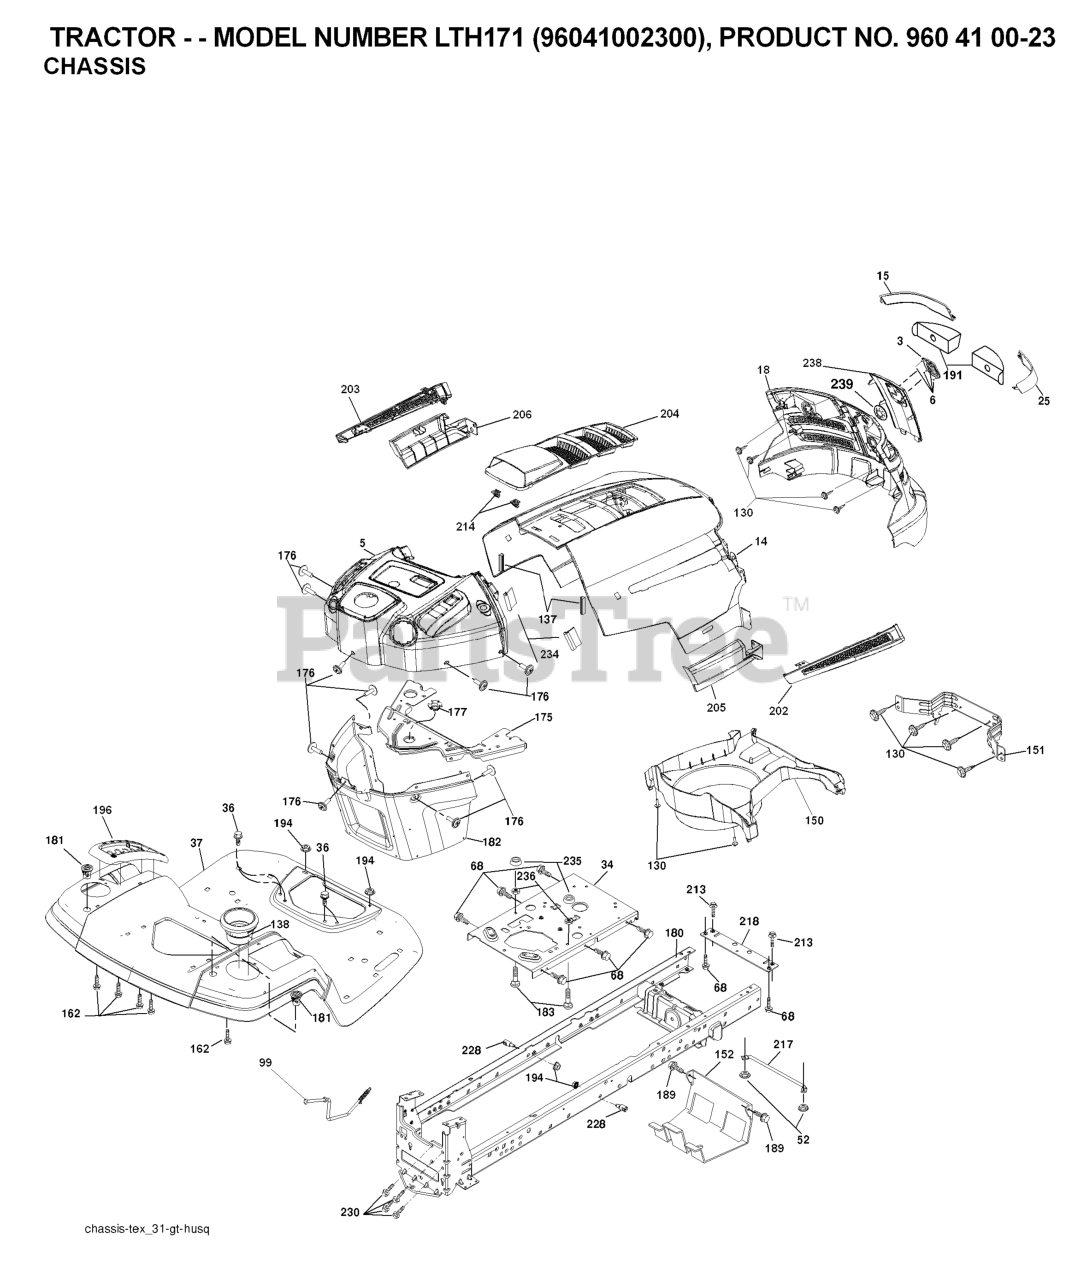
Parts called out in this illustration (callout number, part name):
3	RP LOGO
5	DASH
14	HOOD
15	LENS.HUSQVARNA LT.LH
18	RP GRILLE/LENS ASM.
25	LENS.HUSQVARNA LT.RH
34	PLATE.ENGINE.WELDED.CHASSIS
36	SCREW 3/8-16X3/4
37	FENDER.REAR.ORANGE
52	LOCKNUT
68	Screw 5/16-18 x 1/2 Hex, Self Tapping 5/16-18 x 1/2
99	ROD.ASM.BYPASS.0510.HYDRO.LT
130	SCREW
137	BUMPER DASH
138	CUPHOLDER.TL.TEX.418
151	BRACKET PIVOT
152	SHIELD.BROWNING.W/TEX
162	SCREW.HI-LO.CONSOLE
175	CROSSMEMBER
176	SCREW.#10-24X5/8.RN.QU
177	BUSHING STEERING
180	CHASSIS
181	BUSHING.MNT.FEND.CRGO.
182	DASH LOWER
183	BOLT.5/16-18X1-1/4 FULL.THREAD
189	SCREW
191	INSERT REFLECTIVE
194	NUT LOCK HEX FLANGE 5/16-18
196	CONSOLE.ASM.DECK.LIFT.
202	VENT SIDE HOOD RH
203	VENT SIDE HOOD LH
204	VENT TOP HOOD
205	SKIRT SIDE RH
206	SKIRT SIDE LH
213	BOLT
214	CLIP.RETAINER.TINNER.
217	ROD PIVOT CHASSIS/HOOD
218	X-PIECE.HOOD.STOP.NON/
228	STUD.FASTNER.W/ANTI-ROTATE
230	SHOULDER BOLT 5/16-18TT
234	BUMPER.HOOD.TEX.HUSQVARNA
235	SPACER FENDER
236	NUT.CENTERLOCK.5/16-
238	TRIM
